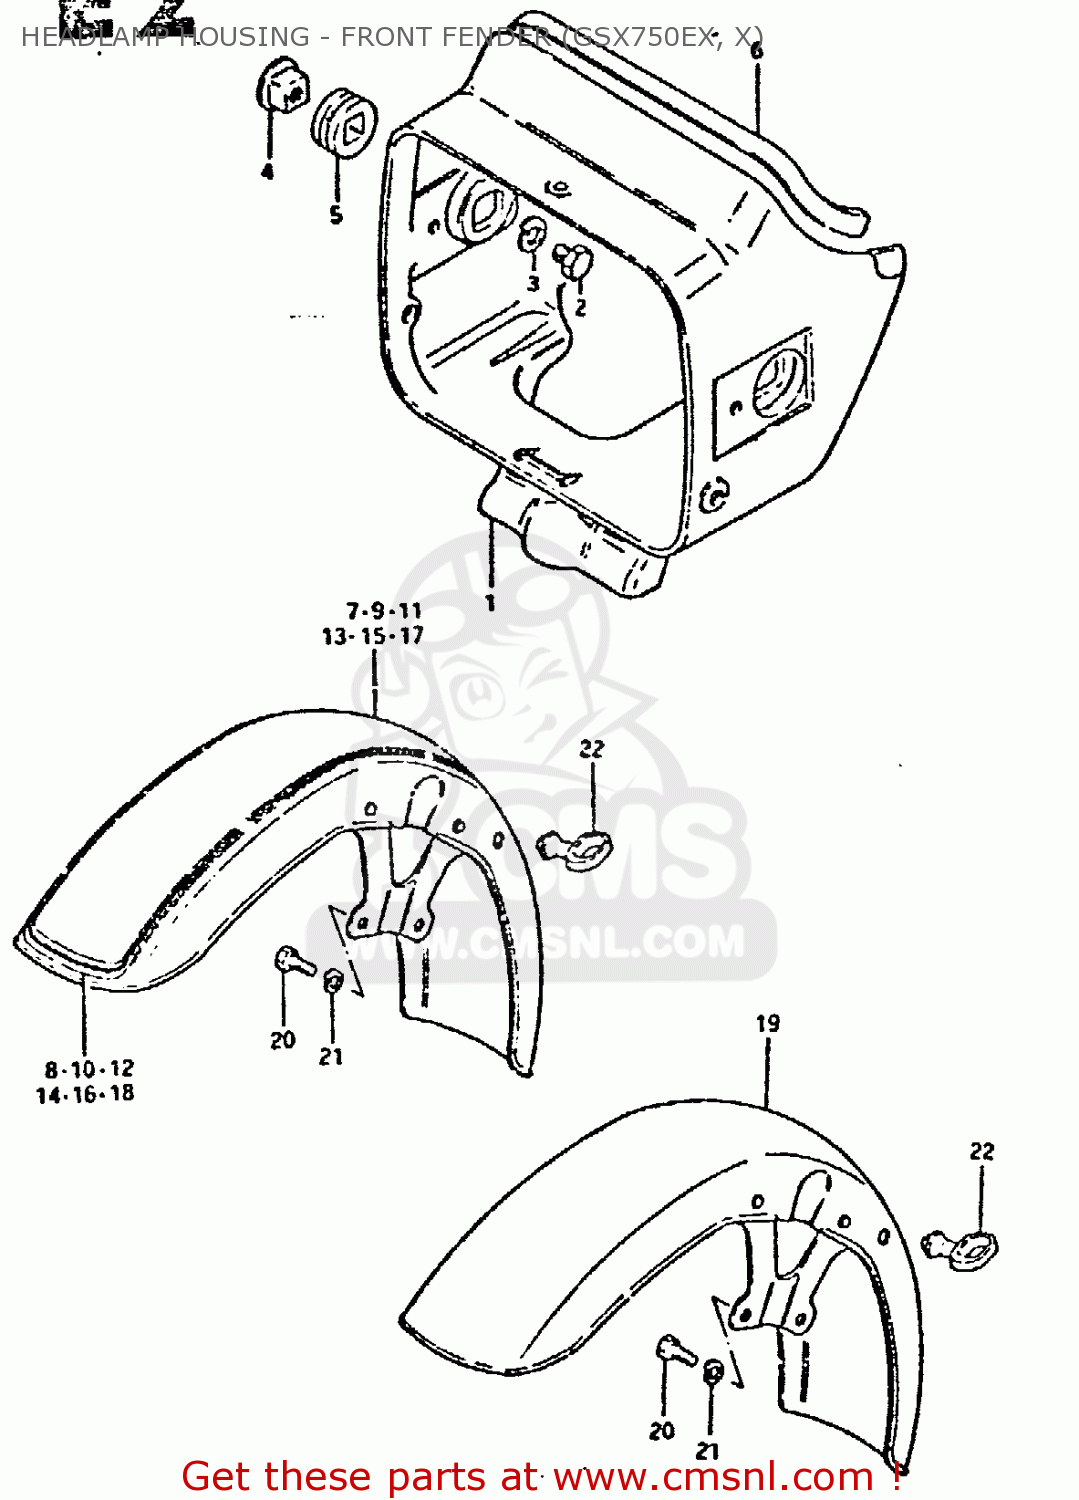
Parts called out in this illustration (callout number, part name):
1	HOUSING, HEADLAMP
2	BOLT
3	LOCK WASHER
4	SPACER,HEADLAMP HOUSING
5	CUSHION,HEADLAMP HOUSING
6	MOLDING,HEADLAMP HOUSING
7	FENDER, FRONT
8	TAPE
9	FENDER, FRONT
10	TAPE
11	FENDER, FRONT
12	TAPE
13	FENDER, FRONT
14	TAPE
15	FENDER, FRONT
16	TAPE
17	FENDER, FRONT
18	TAPE
20	BOLT
21	LOCK WASHER
22	GUIDE,CABLE
